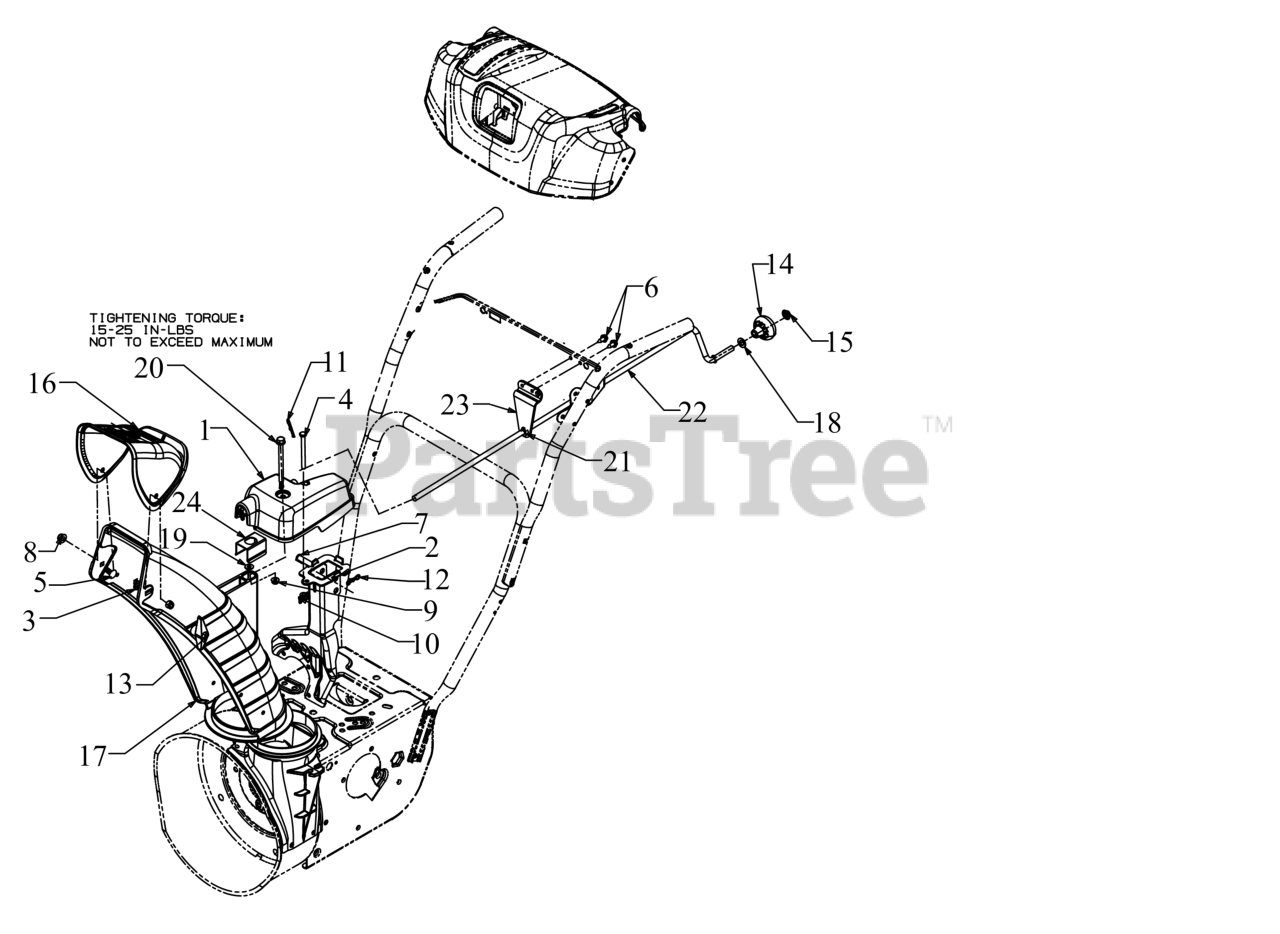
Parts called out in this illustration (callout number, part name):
1	WORM GEARBOX ASSEMBLY
2	CHUTE SUPPORT BRACKET ASSEMBLY
3	CARRIAGE BOLT 5/16-18 x 1
4	SCREW 1/4-20 x 3.0 GR5
5	CARRIAGE BOLT 5/16-18 x .75
6	SCREW 1/4-20X.625
7	CLEVIS PIN 3/8 x 1.87
8	FLANGE LOCK NUT 5/16-18
9	FLANGE LOCK NUT
10	WING NUT 1/4-20
11	INTERNAL COTTER PIN
12	BOW TIE COTTER PIN 1/4-5/16
13	WING NUT KNOB
14	SHIFT KNOB
15	PUSH NUT
16	UPPER CHUTE
17	LOWER CHUTE 5" DIA
18	FLAT WASHER
19	FLAT WASHER
20	SHOULDER SCREW
21	BUSHING .380 ID
22	CHUTE CRANK
23	ROD SUPPORT BRACKET
24	CHUTE BRACKET
